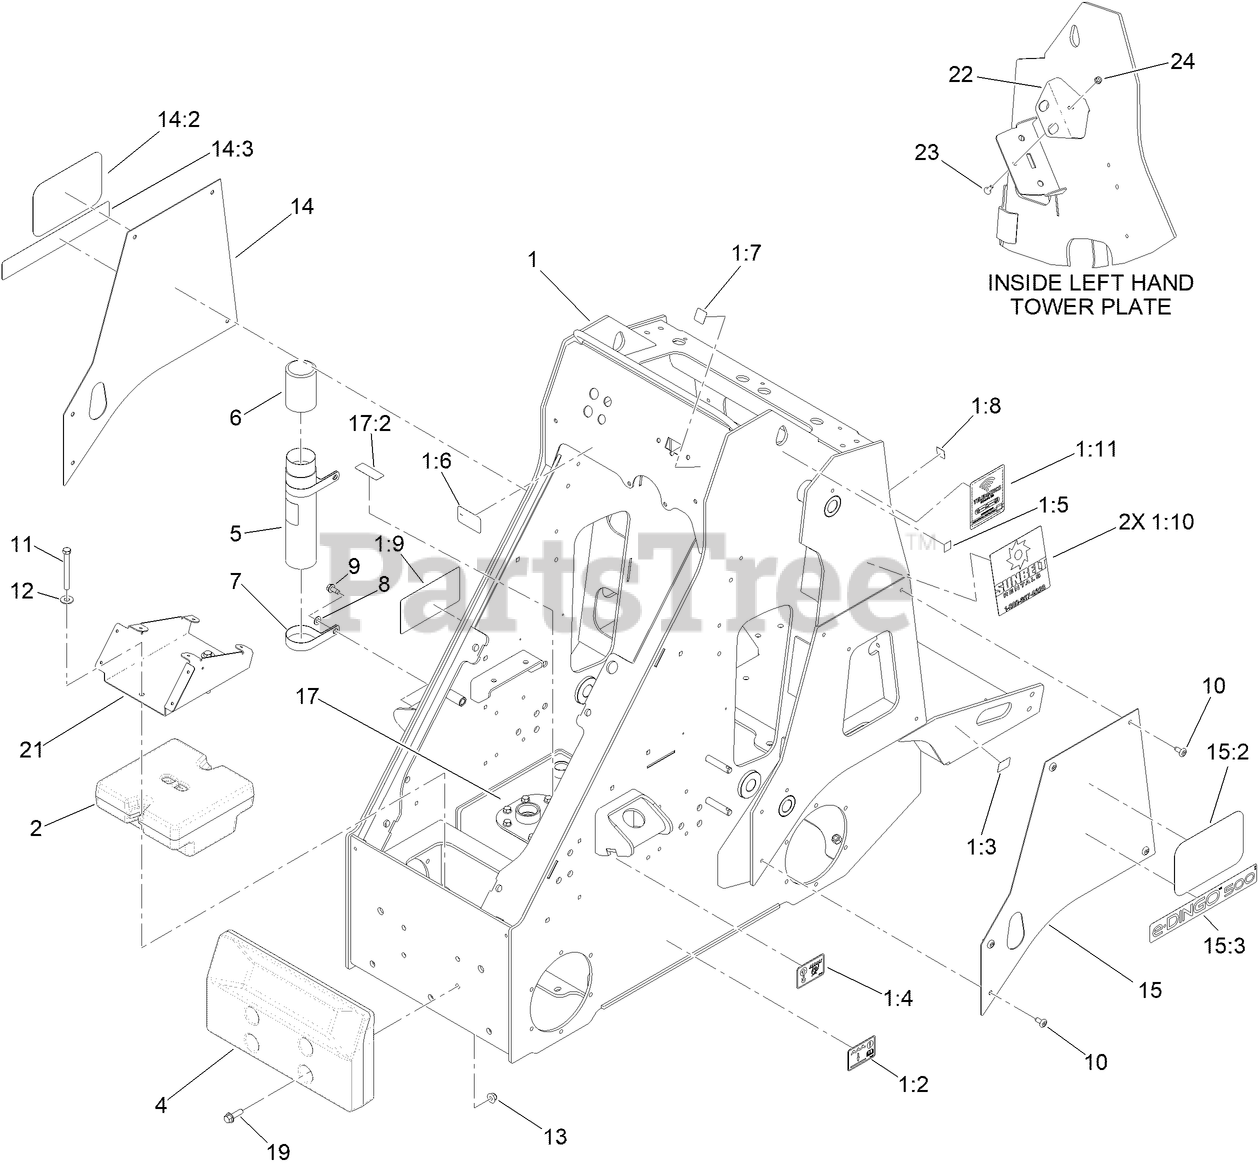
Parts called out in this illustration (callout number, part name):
1	MAIN FRAME ASM [SUNBELT]
1:2	DECAL-WATER LEVEL
1:3	DECAL-TIEDOWN
1:4	DECAL-LIFT/TIE DOWN
1:5	DECAL-POINT, LIFT
1:6	DECAL - FUSES
1:7	DECAL-LIGHT, WARNING
1:8	DECAL-GROUND, EARTH
1:9	DECAL - QUICK REFERENCE AID
1:10	DECAL-S8VSW6X6
1:11	DECAL-TELEMATICS-SBR
2	COUNTERWEIGHT-FRONT
4	COUNTERWEIGHT-FRONT
5	TUBE-MANUAL
6	CAP-HOUSING
7	CLAMP-R
8	WASHER-PLAIN
9	SCREW-HWHTF
11	SCREW-HH
12	WASHER-FLAT
13	NUT-HF, NI
14	PANEL-ACCESS, RH
14:2	DECAL-LOGO, SILVER
14:3	DECAL- E-DINGO
15	PANEL-ACCESS, LH
15:2	DECAL-LOGO, SILVER
15:3	DECAL- E-DINGO
17	PLATE - COVER
17:2	DECAL-OIL, HYD
19	SCREW-HHF
21	BRACKET-MOUNT, FAN
22	BRACKET-FITTING, ADJUSTABLE
23	BOLT-CARR
24	NUT-FLANGE, NI
